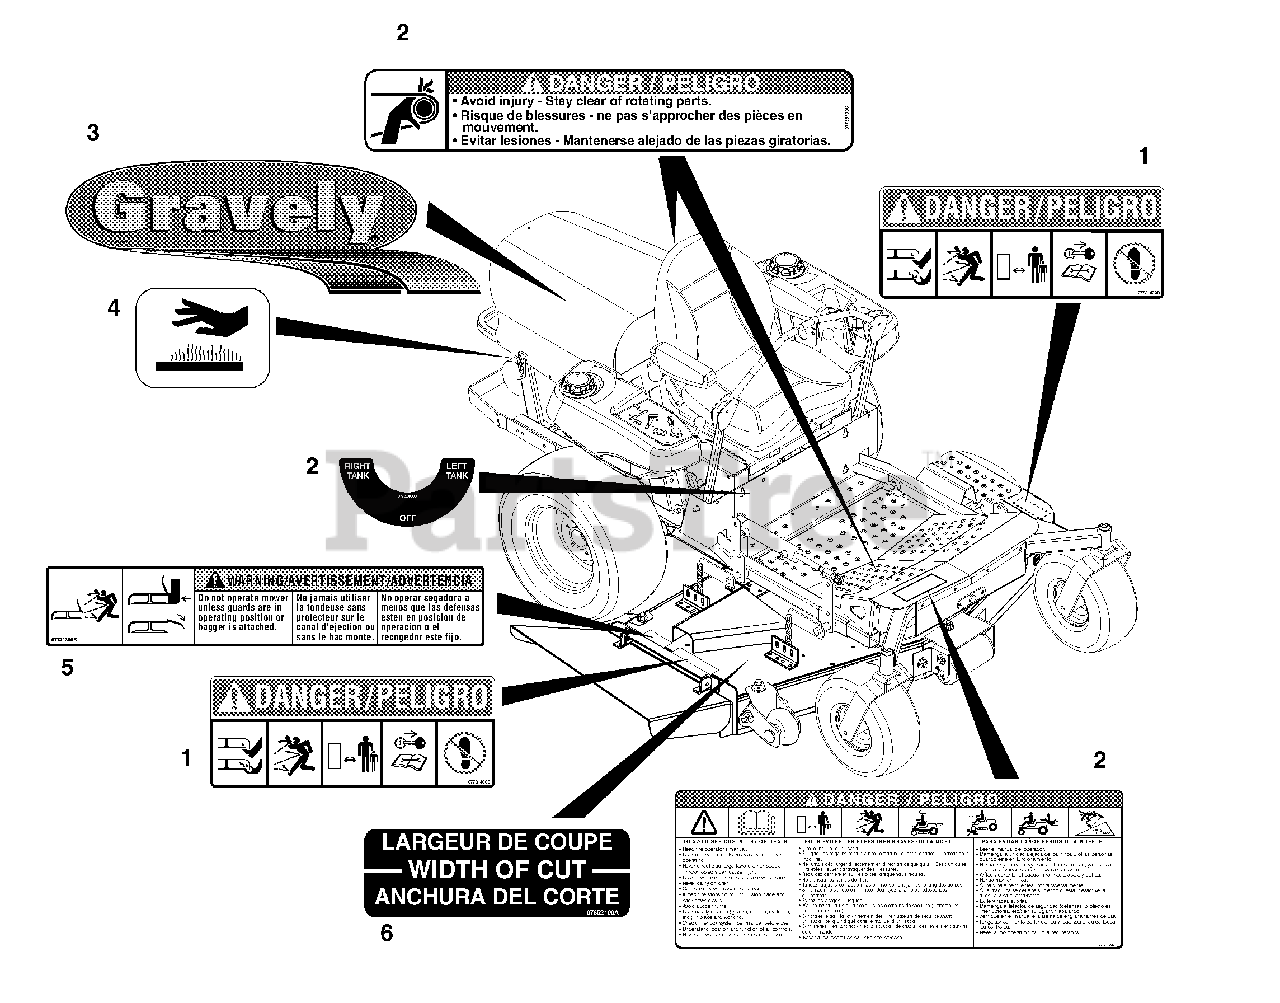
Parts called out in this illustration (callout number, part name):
1	Decal, Mower Pan Head Danger
2	Set, Decal-Common Danger/Fuel
3	Decal Set Gravely Logo
4	Decal-Hot Surface
5	Decal, Warning
6	Decal, Width of Cut
